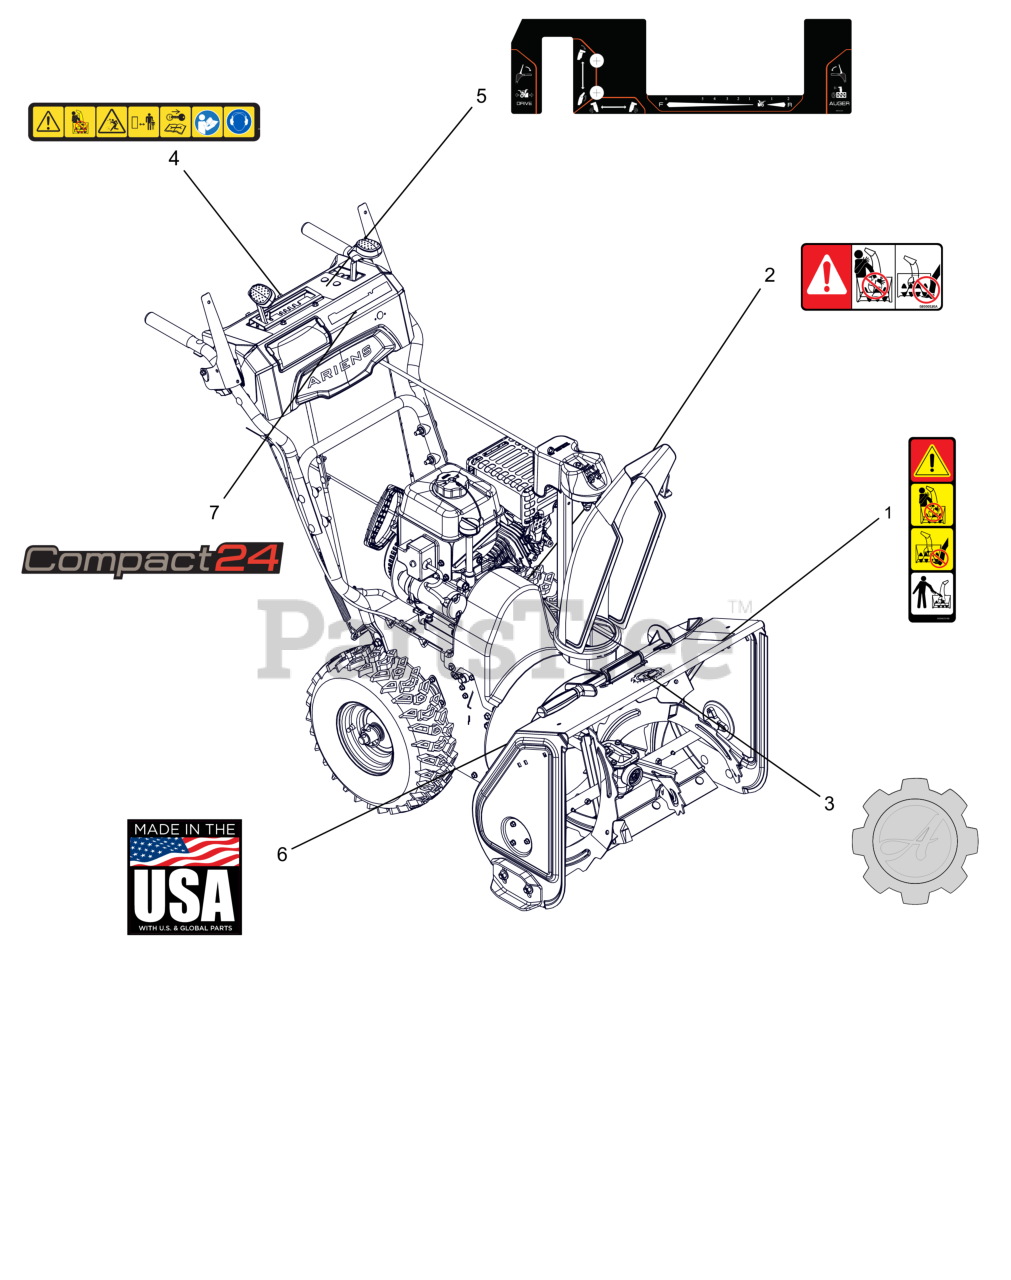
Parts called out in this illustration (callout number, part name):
1	DECAL, DANGER - ROTATING PARTS
2	DECAL, DANGER
3	DECAL, ARIENS-GEAR BADGE -THK
4	DECAL,DASH - SAFETY
5	DECAL,CONTROL-COMP REMOTE
6	DECAL, MADE IN USA
7	DECAL, DASH - COMPACT 24
